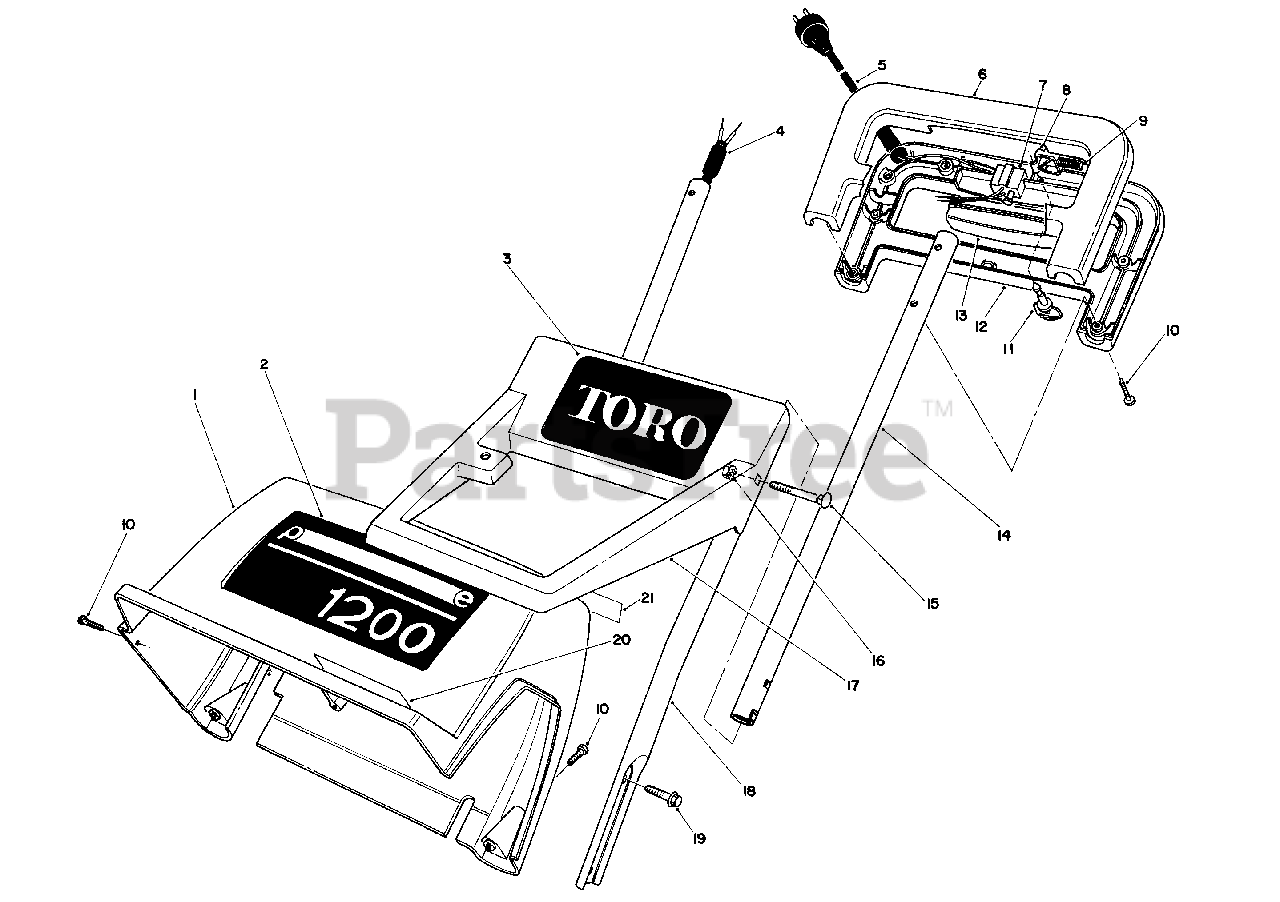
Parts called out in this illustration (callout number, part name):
1	Shroud (Incl. Ref. #2, 20, & 21)
2	Decal-1200
3	Decal-Toro
4	Wire Harness
5	Cord Supply
6	Handle-Upper Control
7	Switch-Starter
8	Switch-Lockout
9	Spring-Compression
10	Screw-Self Tap. Pan Hd.
12	Handle-Lower Control
13	Bar-Switch
14	Tube-Upper
15	Bolt-Carriage
16	Nut-Lock
17	Handle-Middle
18	Handle-Lower L.H.
20	Decal-Danger
21	Decal-U.L.
